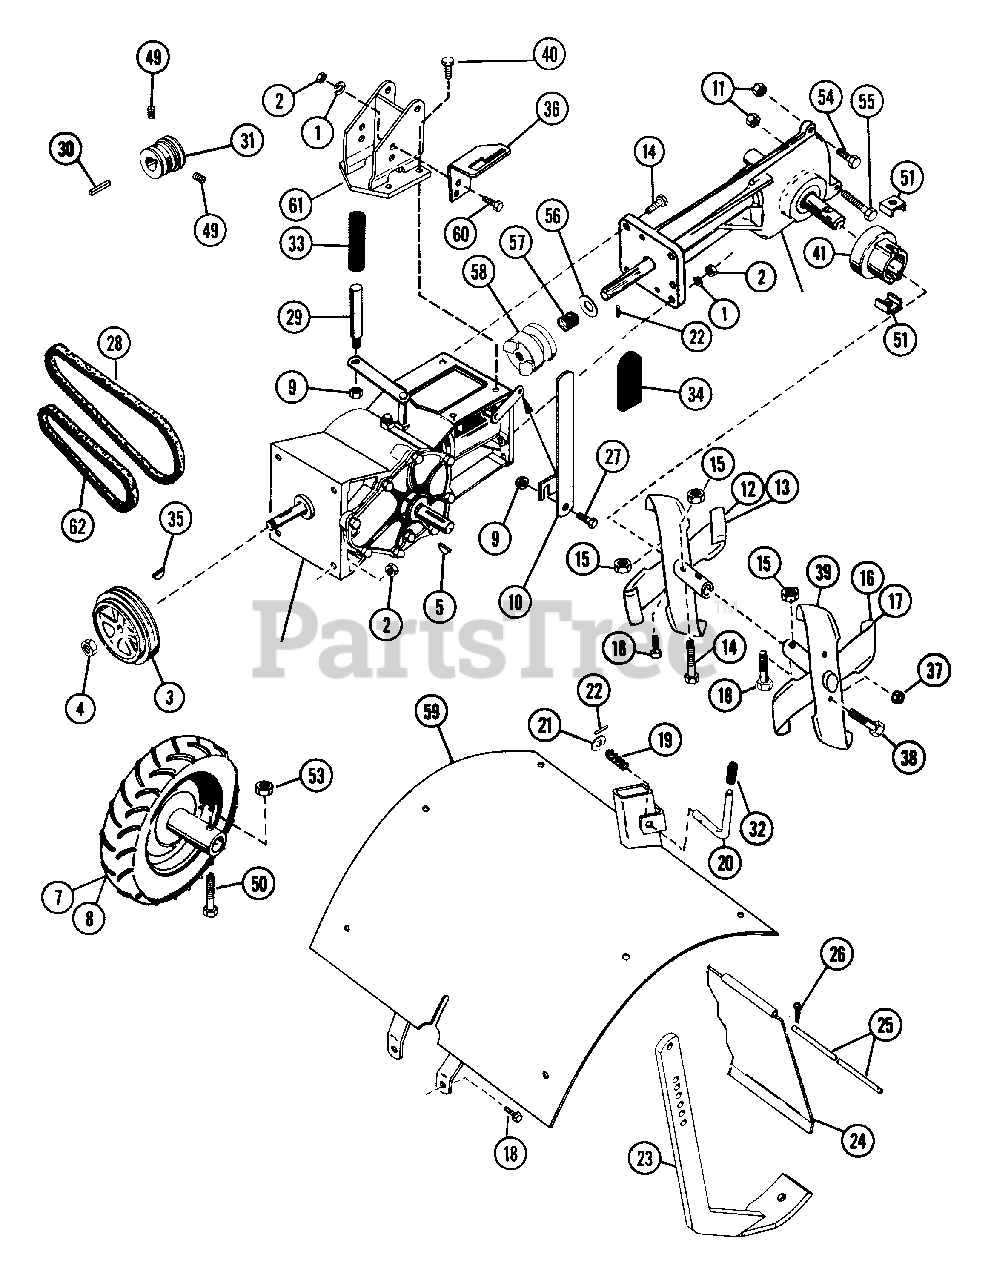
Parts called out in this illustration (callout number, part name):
1	WSHR-LK .375X.115 HVY PL
2	NUT-HEX .375-16
3	DRIVE SHEAVE
4	NUT-LK-CTR .75-16 PL
5	KEY-FTHR .25X1.875X.25 SAE
7	R H TIRE AND RIM ASSEMBLY
8	L H TIRE AND RIM ASSEMBLY
9	NUT-FLG. .312-18 PL
10	ENGAGING ARM
11	NUT-LK .312-18 GR A PL
12	R H INNER TINE SPOOL
13	L H INNER TINE SPOOL
14	BLT-HEX .38-16X1.75 PL GR2
15	NUT-LK-CTR .375-16 GR A PL
16	R H OUTER TINE SPOOL
17	L H OUTER TINE SPOOL
18	BLT-HEX .38-16X2.00 PL GR2
19	SG-COMP .045X.50X1.187
20	DEPTH REGULATING PIN
21	WSHR-FL-STL .38X.875X.083 PL
22	PIN-ROLL .125X1.00
23	DEPTH SHOE
24	TAILBOARD
25	HANDLEBAR
26	PIN COTR .09X.50 PL
27	BLT-HEX .31-18X.63 PL GR 2
28	V-BELT, 4L-WRAPPED
29	CLUTCH ARM
30	KEY-WDRF .125X.625X.250 SAE5
31	ENGINE SHEAVE
33	GRIP
35	KEY-FTHR .188X1.25X.187 SAE
36	QUADRANT
37	NUT-LK-TOP .437-14 GR C PL
38	BLT-HEX .44-14X1.00 GR5
39	L H TURBO-TINE
39	R H TURBO-TINE
40	BLT-HEX .31-18X1.00 PL GR 2
41	DUST CAP
49	SCR-SET .25-20X.25 SKHCUPNY OH
50	BLT-HEX .44-14X2.00 PL GR2
53	NUT-LK .437-14 GR A PL
54	BLT-HEX .31-18X1.25 PL GR2
55	BLT-HEX .31-18X3.50 PL GR2
57	SG-COMP .080X.97X2.18 WLD14
58	TILLER JAW CLUTCH
59	TINE HOOD DECAL
60	BLT-HEX .38-16X1.00 PL
61	HANDLEBAR MOUNT
62	V-BELT, 3L-COGGED
